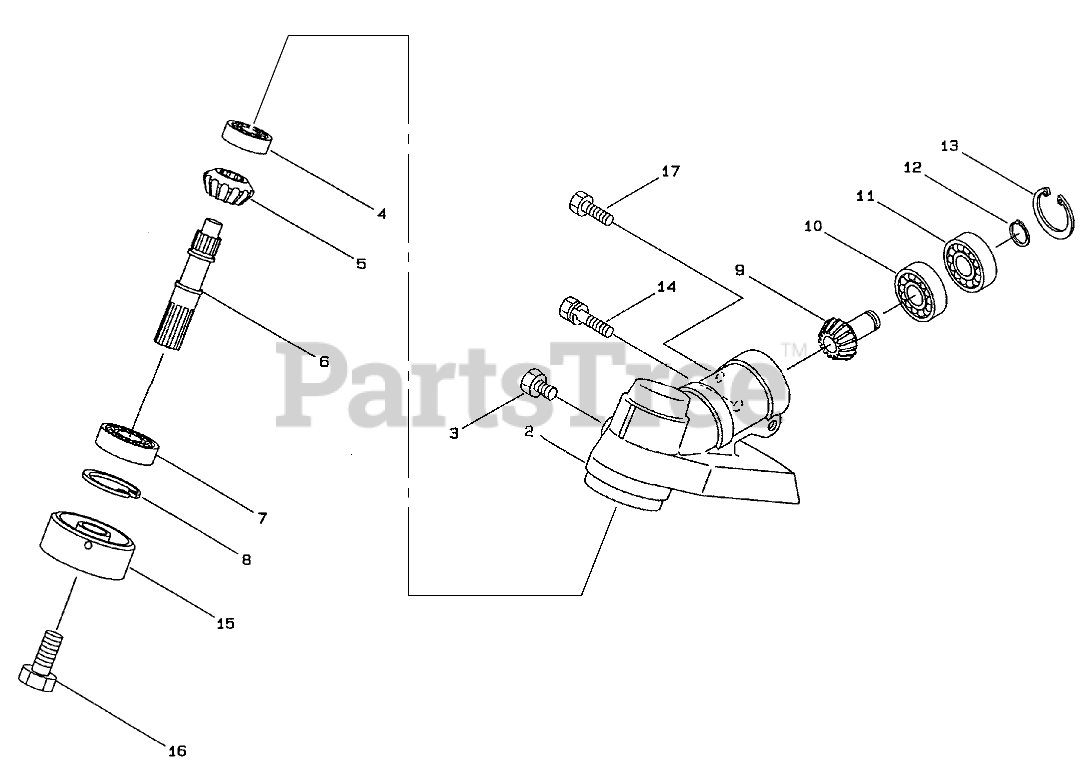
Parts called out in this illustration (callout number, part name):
2	GEARCASE
4	BEARING
6	SHAFT - BLADE
7	BEARING
8	RING - SNAP
9	GEAR - PINION
10	BEARING
11	BEARING
12	RING - SNAP
13	RING - SNAP
15	ADAPTER - BOSS
